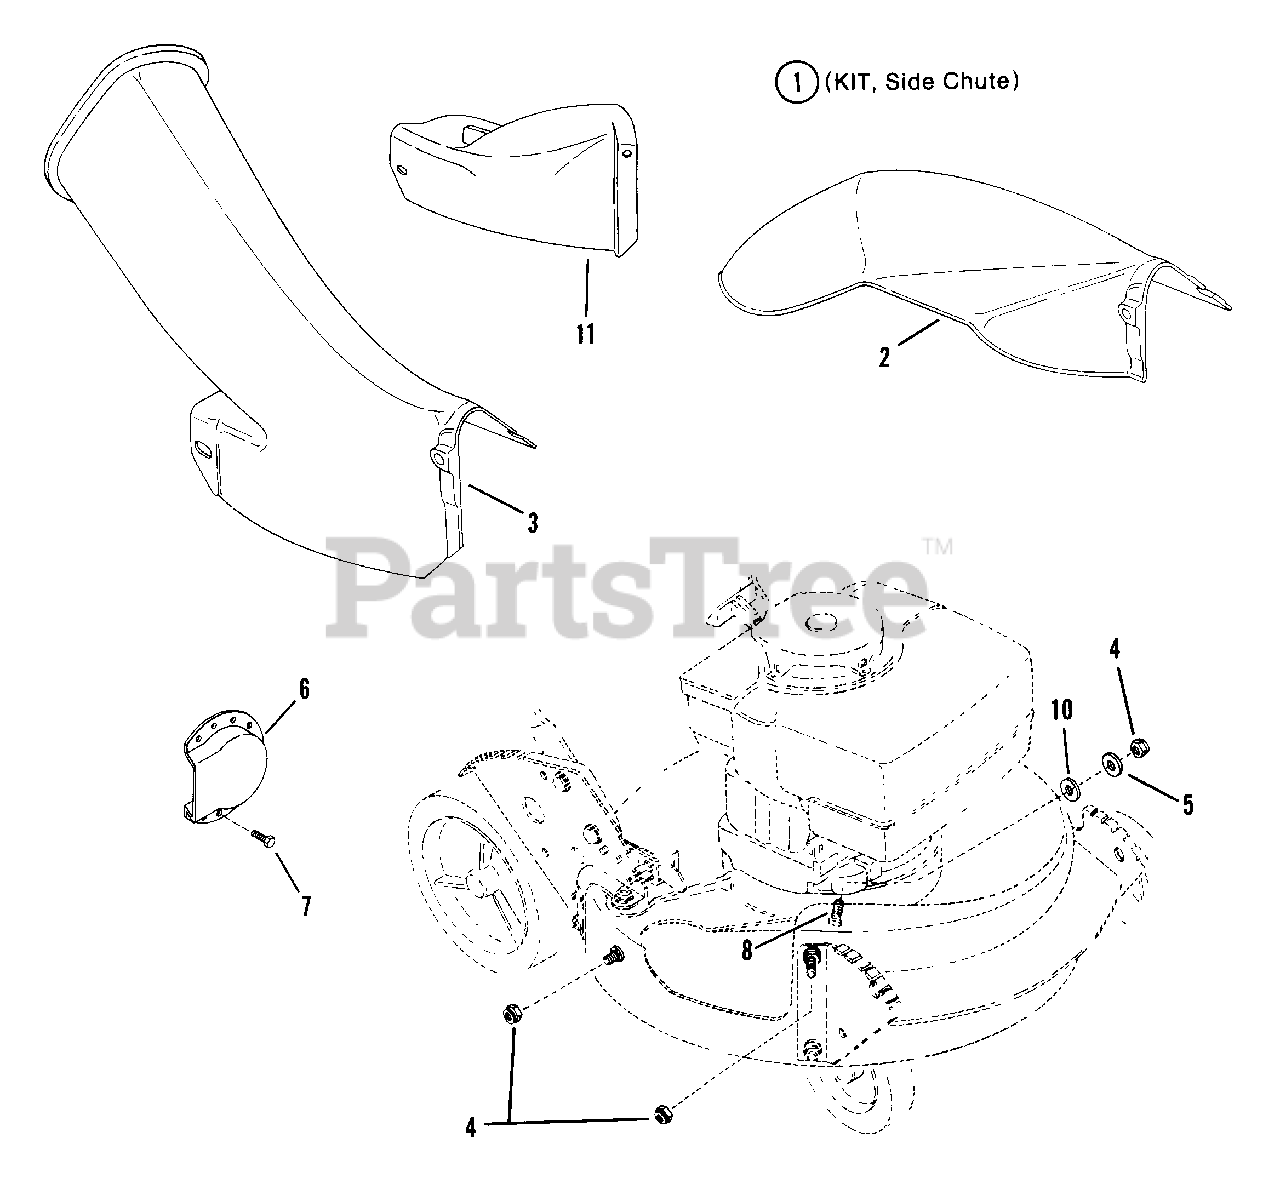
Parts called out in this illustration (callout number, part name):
2	CHUTE, Side
3	ADAPTER, Grass Bag Deck
4	NUT, 5/16-18 Hex Flange Lock
5	WASHER, 5/16 Flat
6	DEFLECTOR, Muffler
7	SCREW, #8-18 x 3/8" Hex Head Cap
8	BOLT, 5/16-18 x 3/4" Carriage
9	RETAINER, 5/16 Bolt
10	WASHER, 5/16 Flat
11	COVER, Deck
